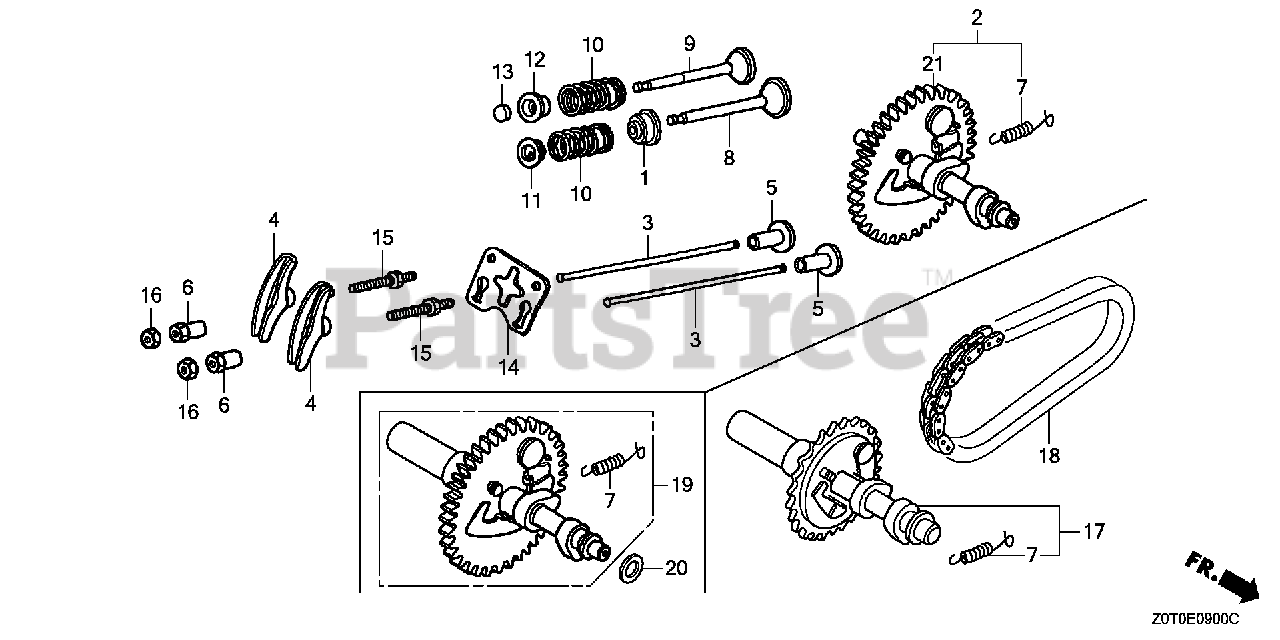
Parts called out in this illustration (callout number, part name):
1	SEAL, VALVE STEM
2	CAMSHAFT ASSY.
4	ARM, VALVE ROCKER
5	LIFTER, VALVE
6	PIVOT, ROCKER ARM
7	SPRING, WEIGHT RETURN
8	VALVE, IN.
9	VALVE, EX.
10	SPRING, VALVE
11	RETAINER, IN. VALVE SPRING
11	RETAINER, VALVE SPRING
12	RETAINER, EX. VALVE SPRING
13	ROTATOR, VALVE
14	PLATE, PUSH ROD GUIDE
15	BOLT, PIVOT (8MM)
16	NUT, PIVOT ADJUSTING
